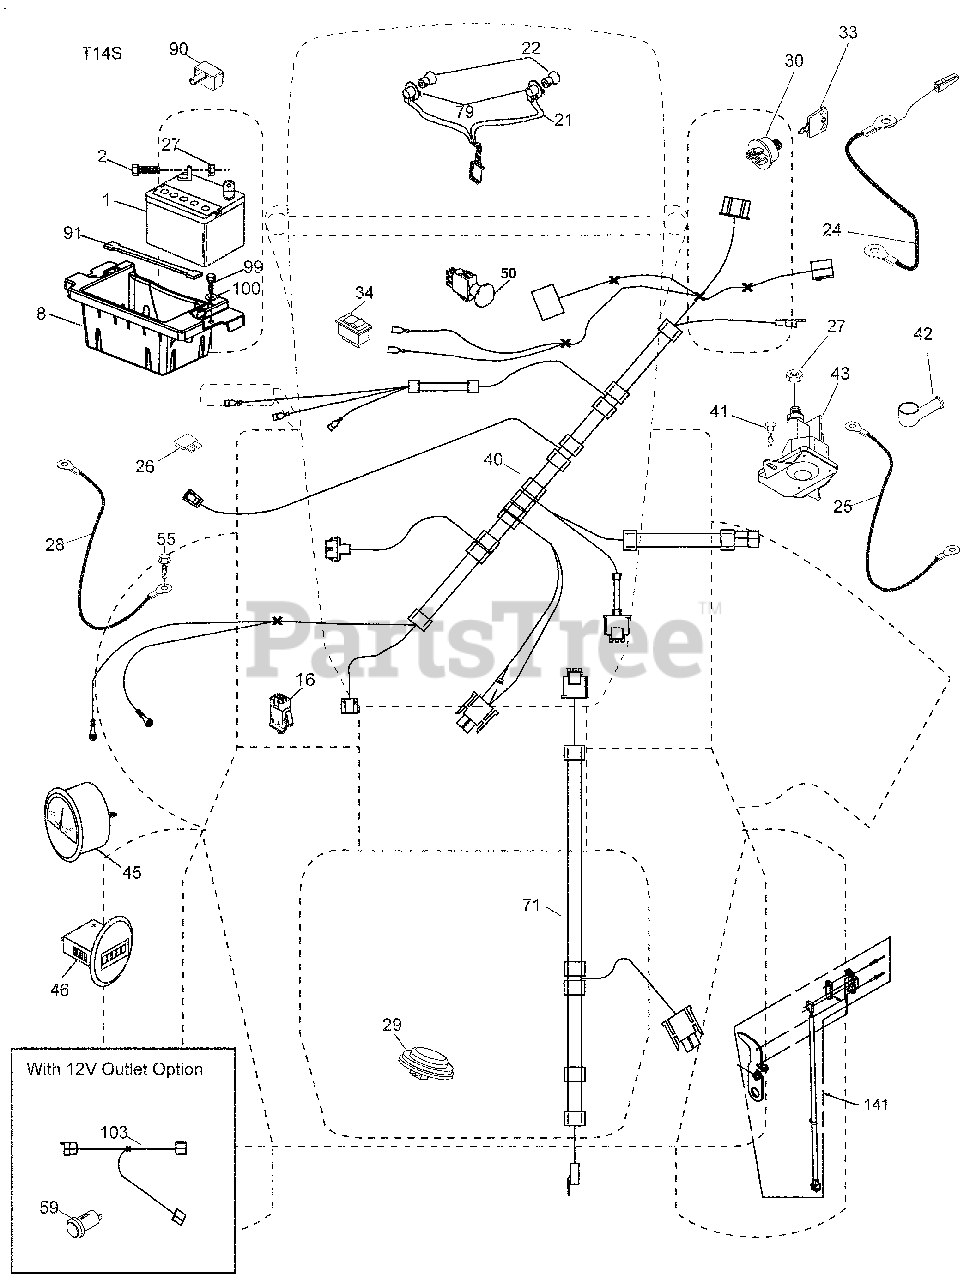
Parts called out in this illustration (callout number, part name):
1	Battery
2	Bolt Hex Hd 1/4-20 unc x 3/4
8	Battery Box
16	Switch Interlock
21	Harness Socket Light
22	Bulb, Light #1156
24	Cable Battery
25	Cable Starter
27	Nut Keps Hex 1/4-20 unc
28	Cable Ground 21" Blk 6 Ga.
29	Switch Seat
30	Switch Ign
34	Switch Light/Reset
40	Harness Ign. Dash
41	Screw 1/4-20 unc x 1/2
42	Cover Terminal Red
43	Solenoid
45	Ammeter Round
46	Gauge Hourmeter
50	Switch PTO
55	Screw Thdrol 5/16-18 x 3/4
59	Outlet 12-Volt
71	Harness Ign
79	Socket Asm. Bulb Twistlock
90	Cover Terminal Battery
91	Strap Battery
99	Screw Hexwsh Thdrol 1/4-20 x 3/4
100	Washer 9/32 x 7/8 x 16 Ga.
103	Harness Pigtail 12V Outlet
141	Kit G700/G730 ROS
